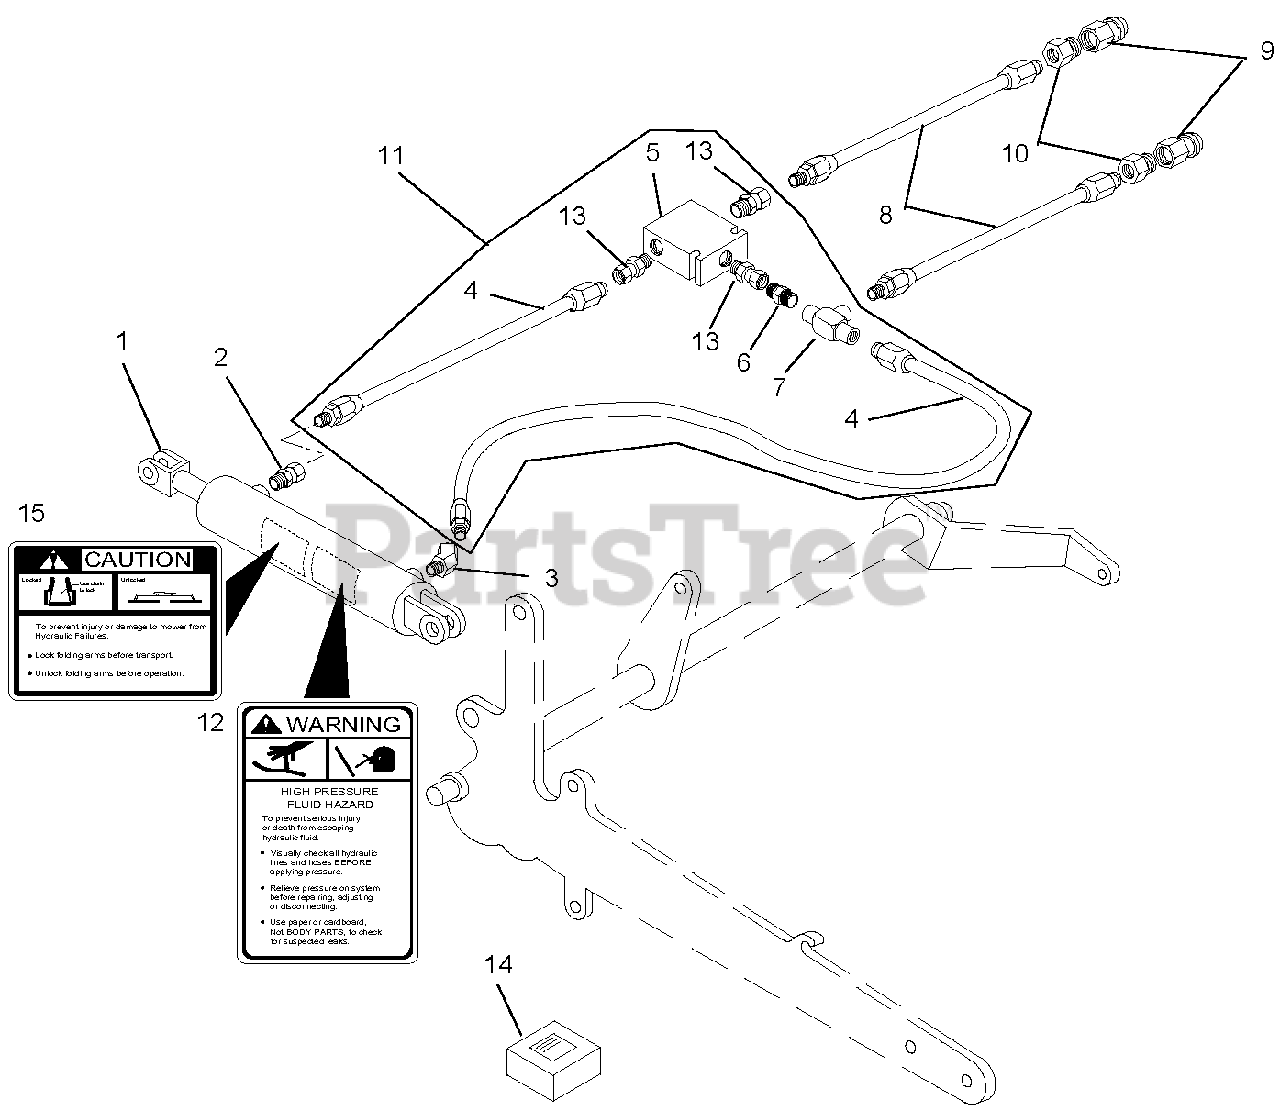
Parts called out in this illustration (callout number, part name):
1	Cylinder, Hydraulic
2	Adapter .25 FNPT x .25 MNPT
3	Adapter .25 FNPT x .25 MNPT
4	Adapter .25 FNPT x .25 MNPT 45-Degree
5	Check Valve
6	Nipple .25 MNPT
7	Tee .25 FNPT
8	Hose Assembly, 120-Inch
9	Coupler, .50 FNPT QD Male
10	Adapter, .50 MNPT x .25 FNPT
11	Check Valve Assembly (Includes Items 4, 5, 6, 7, and 13)
12	Decal, Caution
13	Adapter .25 FNPT x 6 ORB
14	Seal Kit (for 07001007 Hydraulic Cylinder)
15	Decal, Warning
